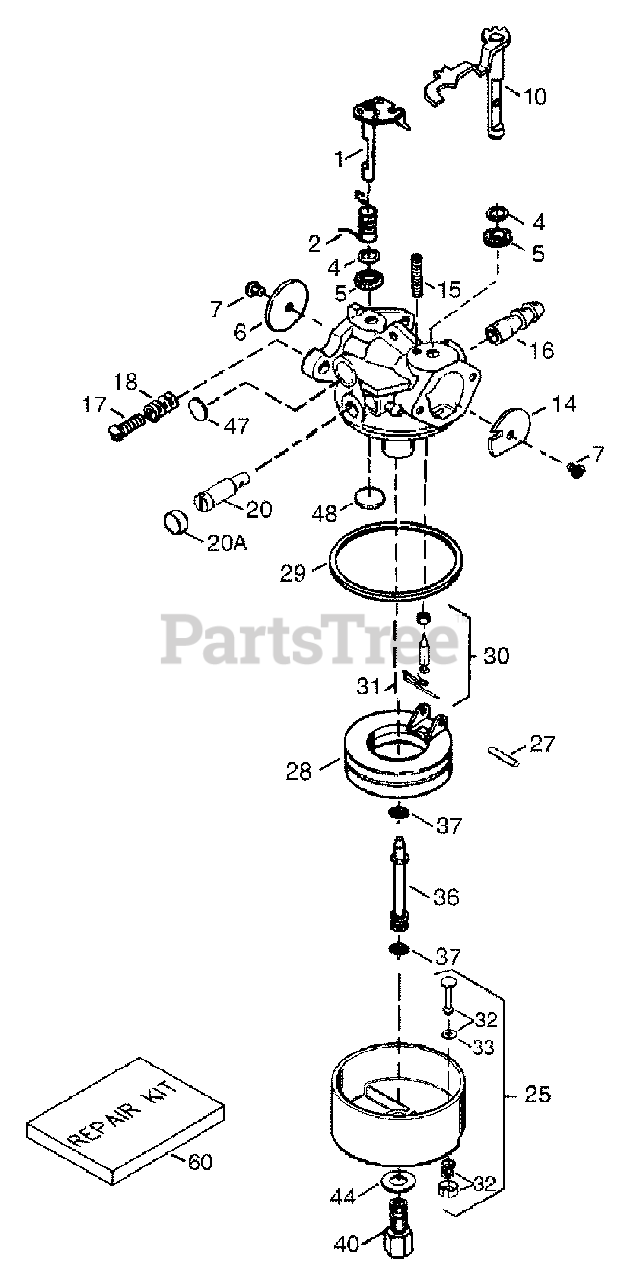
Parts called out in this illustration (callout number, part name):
1	Throttle Shaft & Lever Assembly
2	Throttle Return Spring
4	Dust Seal Washer
5	Dust Seal (Throttle)
6	Throttle Shutter
7	Shutter Screw
10	Choke Shaft & Lever Assembly
14	Choke Shutter
15	Choke Positioning Spring
16	Fuel Fitting
17	Throttle Crack Screw/Idle Speed Screw
18	Tension Spring
20	Idle Restrictor Screw
20A	Idle Restrictor Screw Cap
25	Float Bowl Assembly
27	Float Shaft
28	Float (Plastic)
29	Float Bowl O-Ring
30	Inlet Needle, Seat & Clip
31	Spring Clip
32	Bowl Drain Assembly
33	Drain Plunger Gasket
36	Main Nozzle Tube
37	O-Ring, Main Nozzle Tube
40	High Speed Bowl Nut
44	Bowl Nut Washer
47	Welch Plug, Idle Mixture Well
48	Welch Plug, Atmospheric Vent
60	Repair Kit
